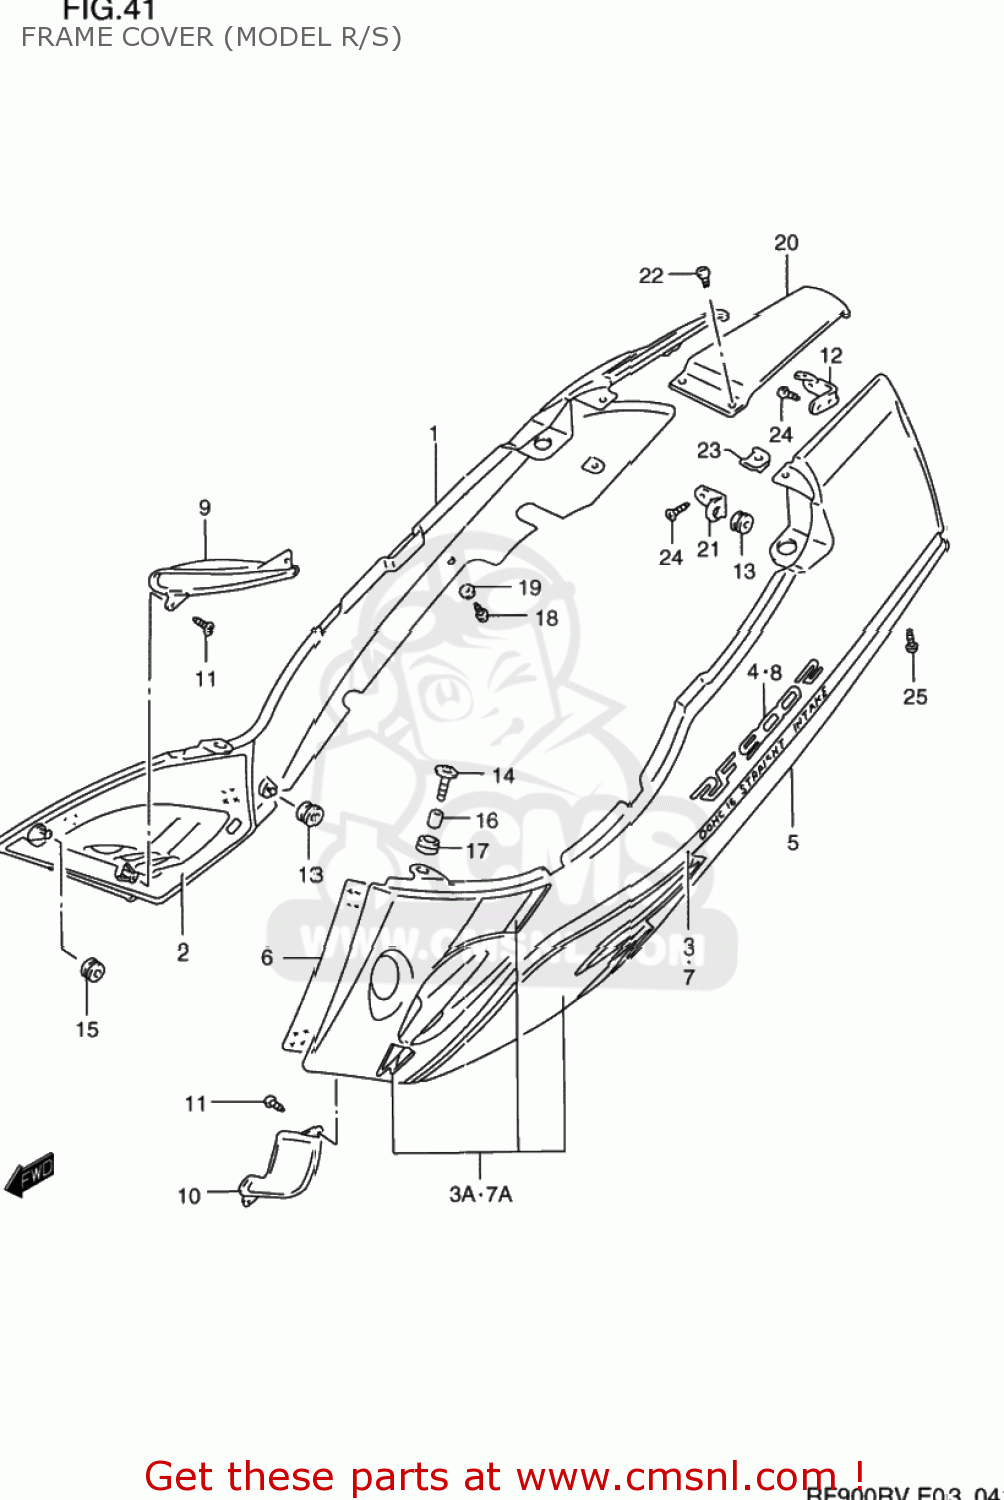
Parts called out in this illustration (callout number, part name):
1	COVER ASSY,FRAME,R(RED)
2	SHIELD,FRAME COVER HEAT
3	TAPE SET,FRAME COVER S
3A	TAPE SET,FRAME COVER,R
4	EMBLEM,FRAME COVER
5	COVER ASSEMBLY,FRAME,LEFT
6	SHIELD,FRAME COVER HEAT,L
7	TAPE SET,FRAME COVER S
7A	TAPE SET,FRAME COVER,LEFT
8	EMBLEM,FRAME COVER
9	COVER,INNER,RIGHT
10	COVER,INNER,L
11	SCREW
12	BRACKET,FRAME COVER,R
13	CUSHION
14	SCREW
15	CUSHION,FRAME COVER FR
16	SPACER
17	CUSHION
18	SCREW 5X12
19	WASHER(5.2X14X1.5)
20	COVER,FRAME CTR
21	BRACKET,RR COMBINATION LAMP
22	SCREW 5X12
23	NUT
24	SCREW
25	SCREW
